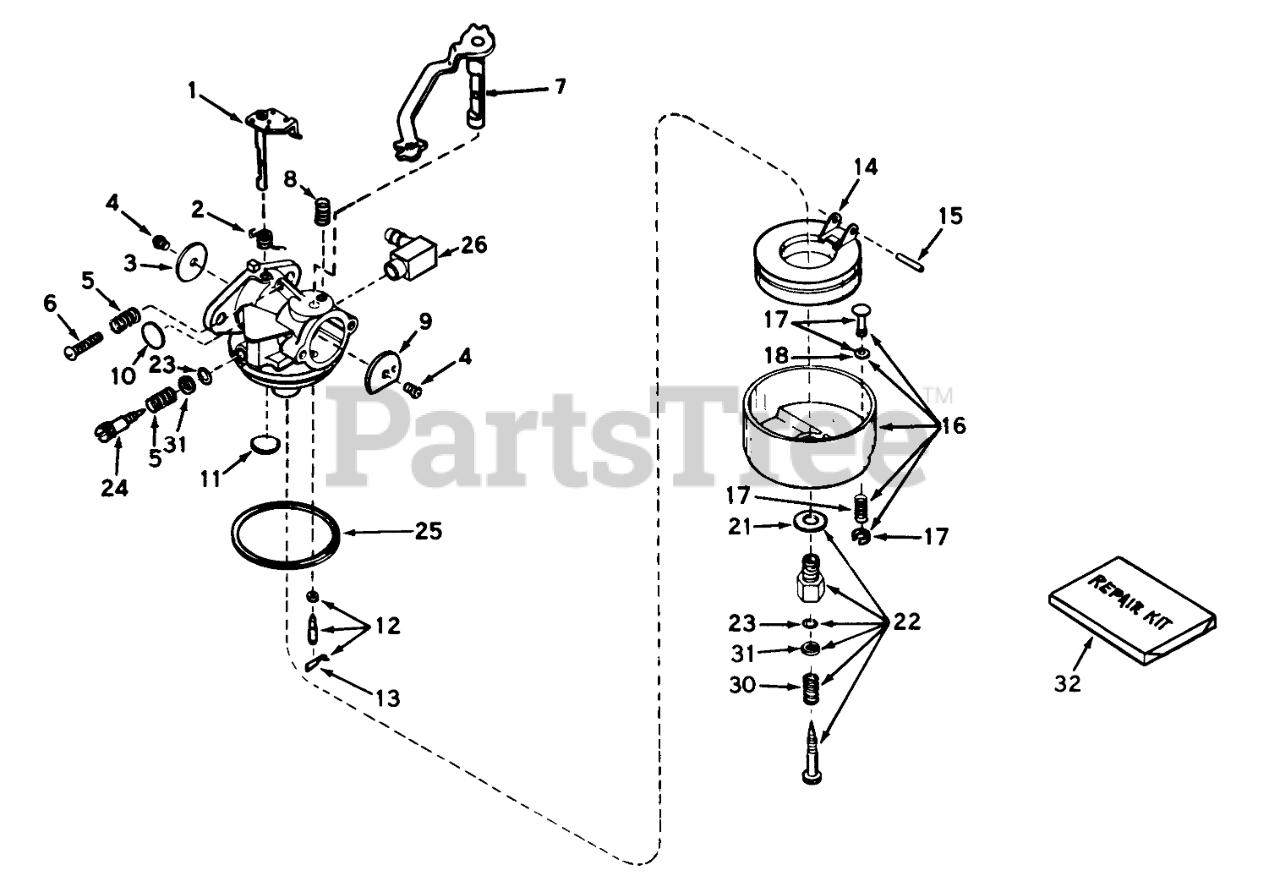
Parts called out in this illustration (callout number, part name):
1	Throttle Shaft and Lever ASM
2	Spring, Throtte Return
3	Shutter-Throttle
4	Screw-Shutter
5	Spring-Tension
6	Screw-Throttle Crack Screw / Idle Speed
7	Shaft & Lever Ass-y, Choke
8	Spring-Positioning, Choke
9	Shutter-Choke
10	Plug-Welch, Idle Mixture Well
11	Plug-Welch, Atmospheric Vent
12	Inlet Needle, Seat & Clip Ass-y (Incl. No. 13)
13	Clip-Spring
14	Float,Carburetor
15	Shaft-Float
16	Bowl & Drain Ass-y, Float (Incl. No. 17)
17	Plunger Ass-y, Drain (Incl. No. 18)
18	Gasket-Plunger, Drain
21	Washer-Bowl Nut
22	Adjustment Screw Ass-y, Main (Incl. Nos. 21, 23, 30 & 31)
23	"O"Ring
24	Screw, Idle Adj.
25	O Ring-Bowl, Float
26	Fitting, Fuel Inlet
32	Kit-Repair
